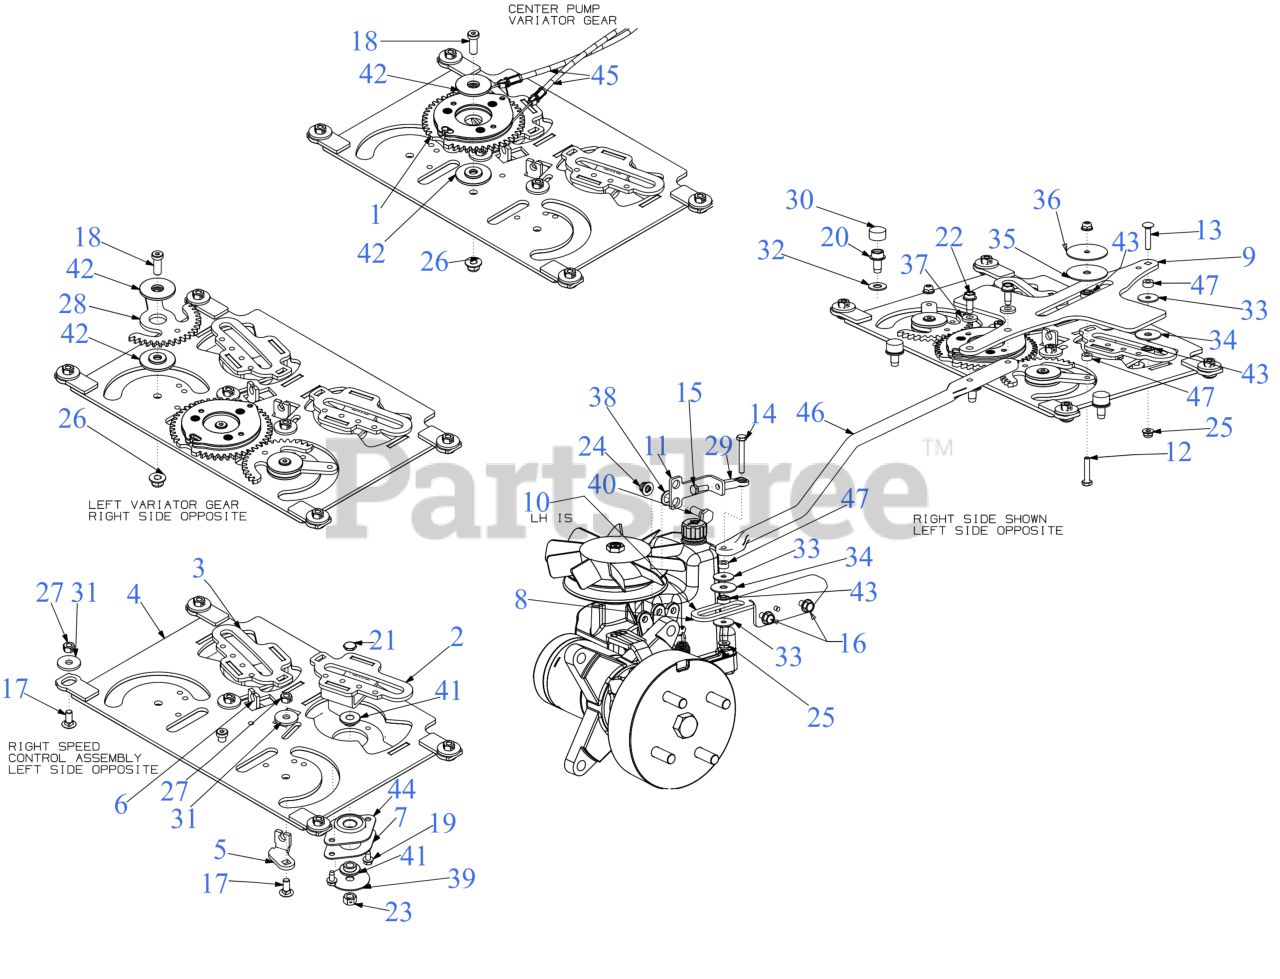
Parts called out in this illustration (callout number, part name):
2	PUMP CONTROL CAM ASSEMBLY (RH)
3	PUMP CONTROL CAM ASSEMBLY (LH)
4	PUMP CONTROL MOUNTING BRACKET
5	STEERING CABLE BRACKET
6	STEERING CABLE BRACKET
7	RETAINING PLATE
8	PUMP ARM GUIDE BRACKET (RH)
9	STEERING PUMP ACTUATOR ARM
11	PUMP CONTROL BRACKET
12	HEX SCREW 1/4-20 x 1.25
13	CARRIAGE BOLT 1/4-20 x 1.25 Gr5
14	HEX SCREW 1/4-20 x 1.75
15	HEX SCREW 1/4-28 x .75
16	SCREW 5/16-18 x .750
17	CARRIAGE BOLT 5/16-18 x .75
18	SCREW 3/8-16 x 1
19	SCREW 1/4-20 X.500
20	SCREW 3/8-16 x 3/4
21	SCREW 3/8-16 x 1.25 GR5
22	SCREW 5/16-18 x .750
24	FLANGE LOCK NUT 5/16-18
25	FLANGE LOCK NUT
28	STEERING GEAR YOKE
29	END ROD (RH)
30	SLIDE CAP
31	FLAT WASHER
32	FLAT WASHER
33	FLAT WASHER
34	WASHER .355X1.25X.06THK
35	FLAT WASHER
36	FLAT WASHER
37	FLAT WASHER.344X.75X.1
38	FLAT WASHER .469X.750X.054
39	HUB CAP WASHER .406 x 1.92 x .060
40	SHOULDER SCREW .437
41	SHOULDER SPACER
42	SHOULDER SPACER
43	BALL BEARING .25 x .625 SPCL
44	BALL BEARING
45	TRANSMISSION CONTROL LINK CABLE
46	CONTROL PUMP ROD
